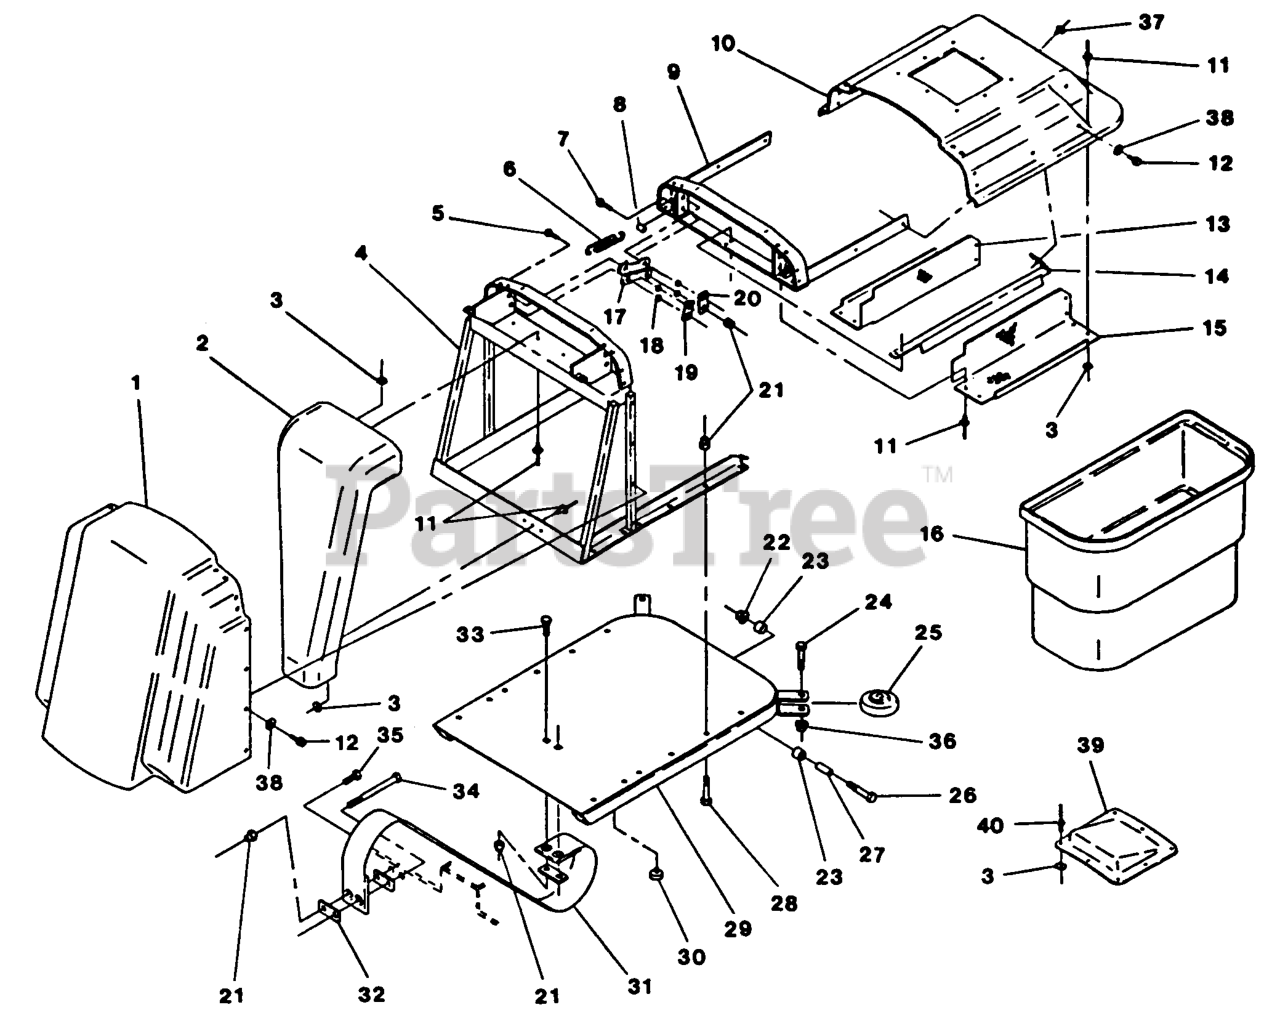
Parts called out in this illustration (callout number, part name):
6	SPRING,CATCHER LID
8	BUSHING,LID SPRING
10	TOP,GRASS CATCHER
13	SCREEN,PERFORATED RH PNT
15	SCREEN,PERFORATED LH PNT
17	LINK,HINGE PLTD
18	BELT,B SIZE 43.5
23	SLEEVE-BEARING
25	WHEEL,RUBBER
27	BUSHING,BOX PIVOT
31	STRAP,BOX RESTRAINT
32	CLAMP,STRAP
33	Bolt, Carriage 1/4-20 X 1
37	Pop Rivet, Steel 3/16 X .250
39	WINDOW,GRASS CATCHER
